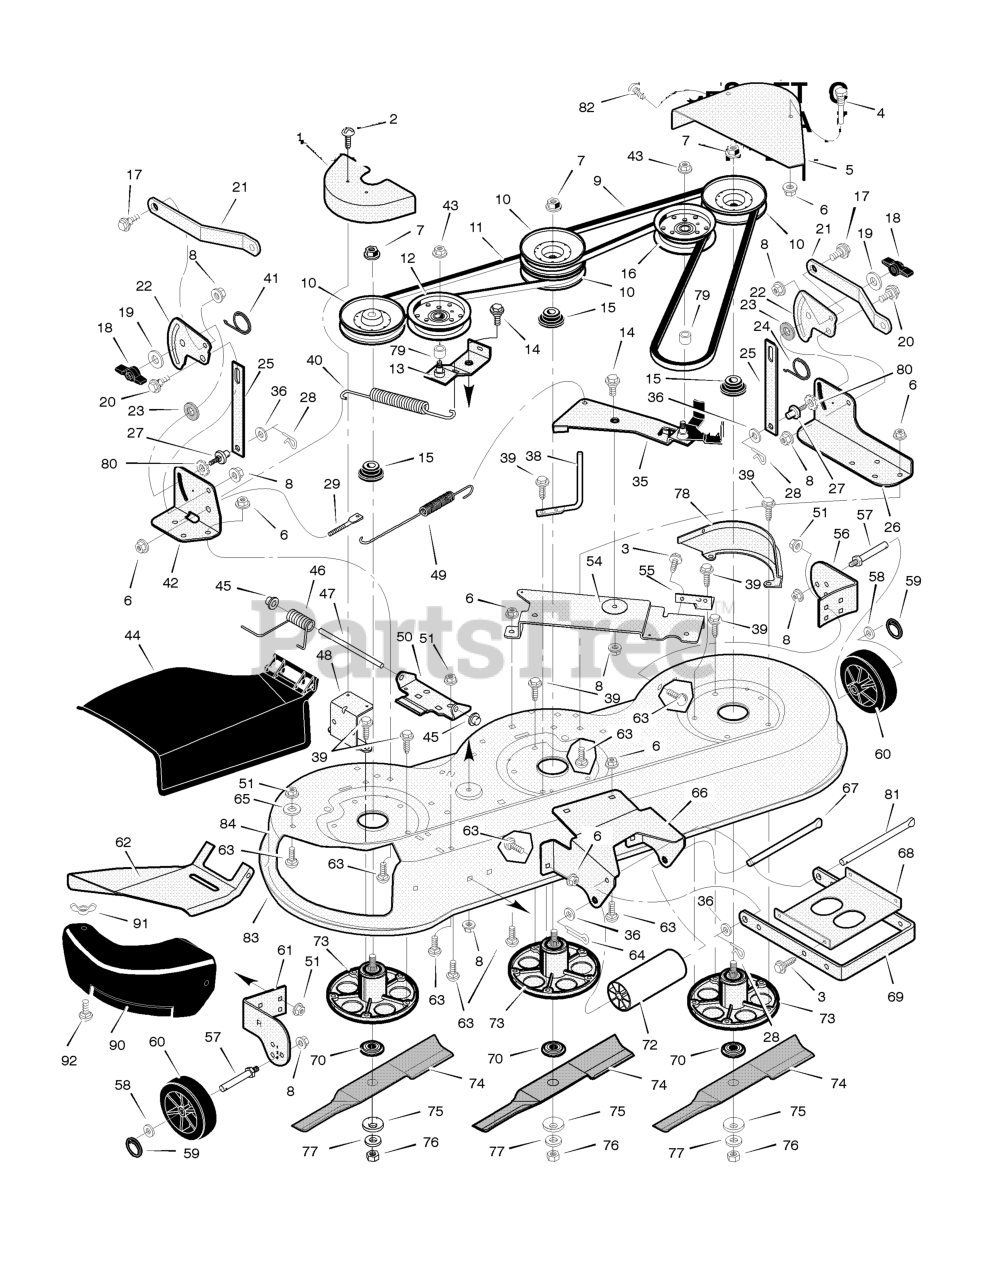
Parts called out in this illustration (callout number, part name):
1	Cover, Right Pulley
2	Screw
4	Guide, Belt
5	Cover, Left Pulley
6	Nut, Hex
7	Nut, Flange
8	Nut, Flange
9	Belt, Primary
10	Pulley
11	Belt, Secondary
12	Pulley, Idler
13	Arm, Idler
14	Bolt, Shoulder
15	Spacer, Pulley
16	Pulley, Idler
17	Bolt, Shoulder
18	Knob
20	Bolt, Shoulder
21	Bracket, Rear Suspension
22	Plate, Suspension
23	Pad, Friction
25	Link, Lift
26	Bracket, Left Lift
27	Pin, Hanger
28	Pin, Hair
29	Rod, Adjuster
35	Idler, Arm
38	Guide, Belt
39	Screw
40	Spring, Extension
41	Spring, Torsion
42	Bracket, Suspension
43	Nut
44	Deflector, Chute
45	Push On Cap
46	Spring, Torsion
47	Rod, Deflector
48	Bracket, Cover
49	Spring, Extension
50	Bracket, Hinge
51	Nut, Flange
54	Plate, Brake Arm
55	Bracket, Brake Plate
56	Bracket, Left Gauge Wheel
57	BOLT, Gauge Wheel
59	Ring, Locking
60	Wheel, Gauge
61	Bracket, Right Gauge Wheel
62	Deflector, Inside
63	Bolt, Carriage
64	Pin, Cotter
66	Bracket, Front Deck
67	Rod, Hanger
68	Stiffener
69	Bracket, Suspension
70	Adapter, Blade
73	Housing, Jackshaft
75	Washer, Belleville
78	Bracket, Pulley Cover
81	Rod, Hanger
90	Cover, Mulch
91	Wingnut
92	Bolt, Carriage
